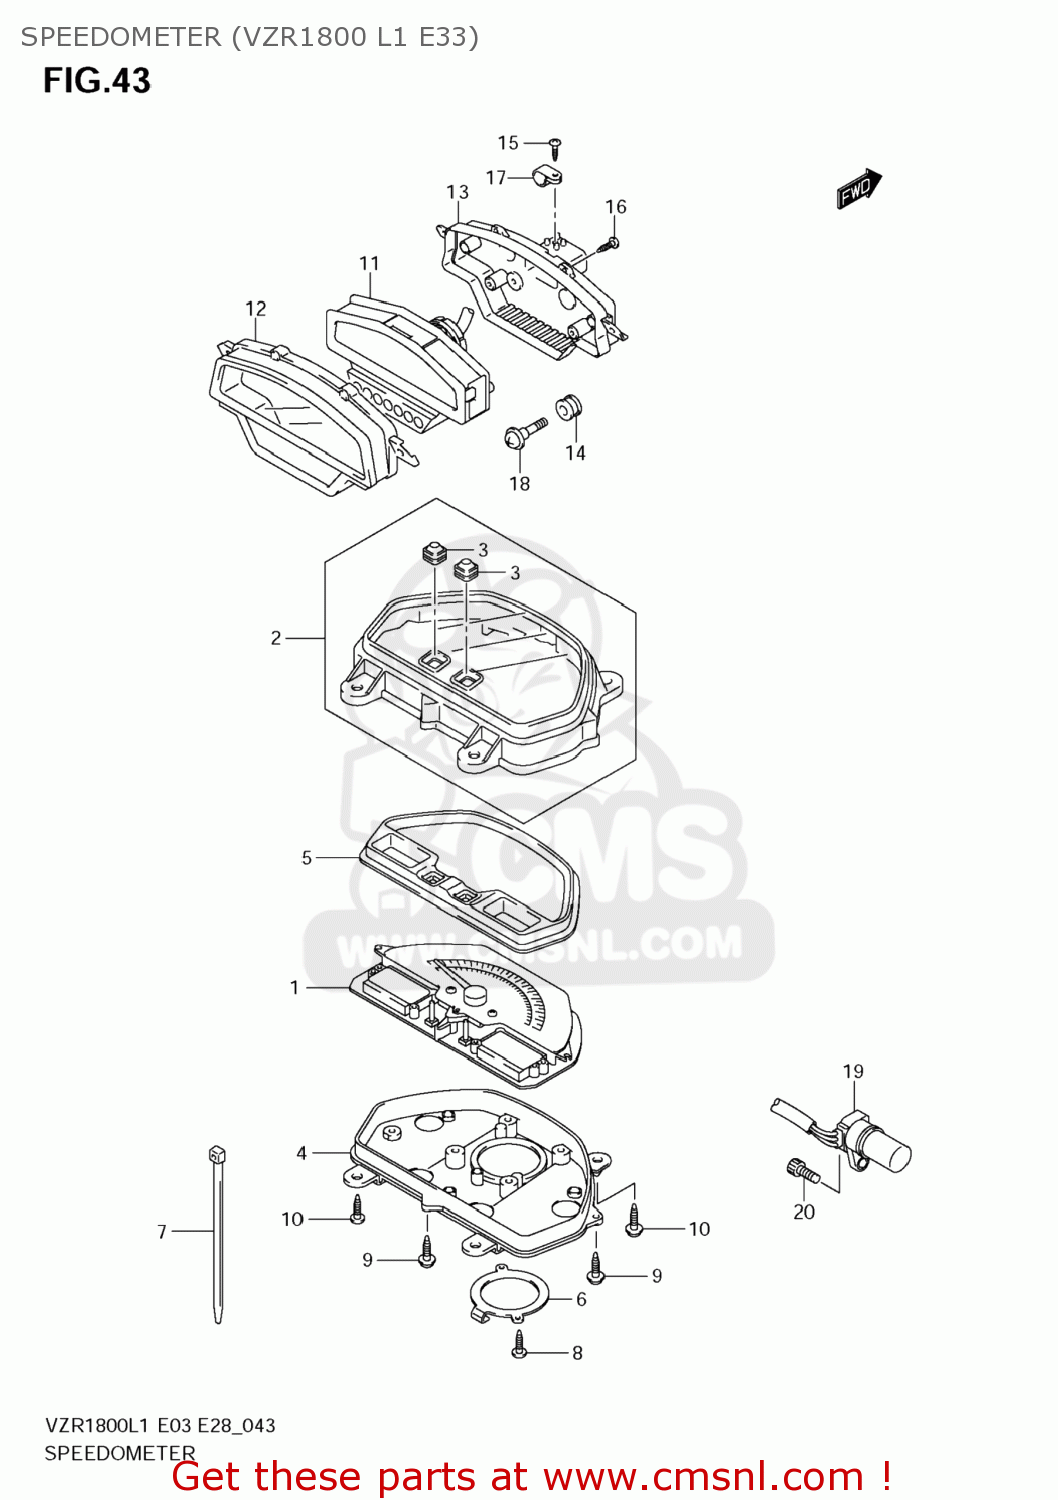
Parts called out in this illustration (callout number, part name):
1	SPEEDOMETER
2	UPR CASE ASSY
3	RUBBER,SWITCH
4	LWR CASE
5	REFLECTOR ASSY
6	BRACKET
7	CLAMP
8	SCREW(3X12)
9	SCREW(3X14)
10	SCREW
11	TACHOMETER ASSY
12	CASE ASSY,UPR
13	CASE ASSY,LWR
14	CUSHION
15	SCREW(4X14)
16	SCREW(3X16)
17	CLAMP
18	SCREW
19	SENSOR,SPEED
20	BOLT
